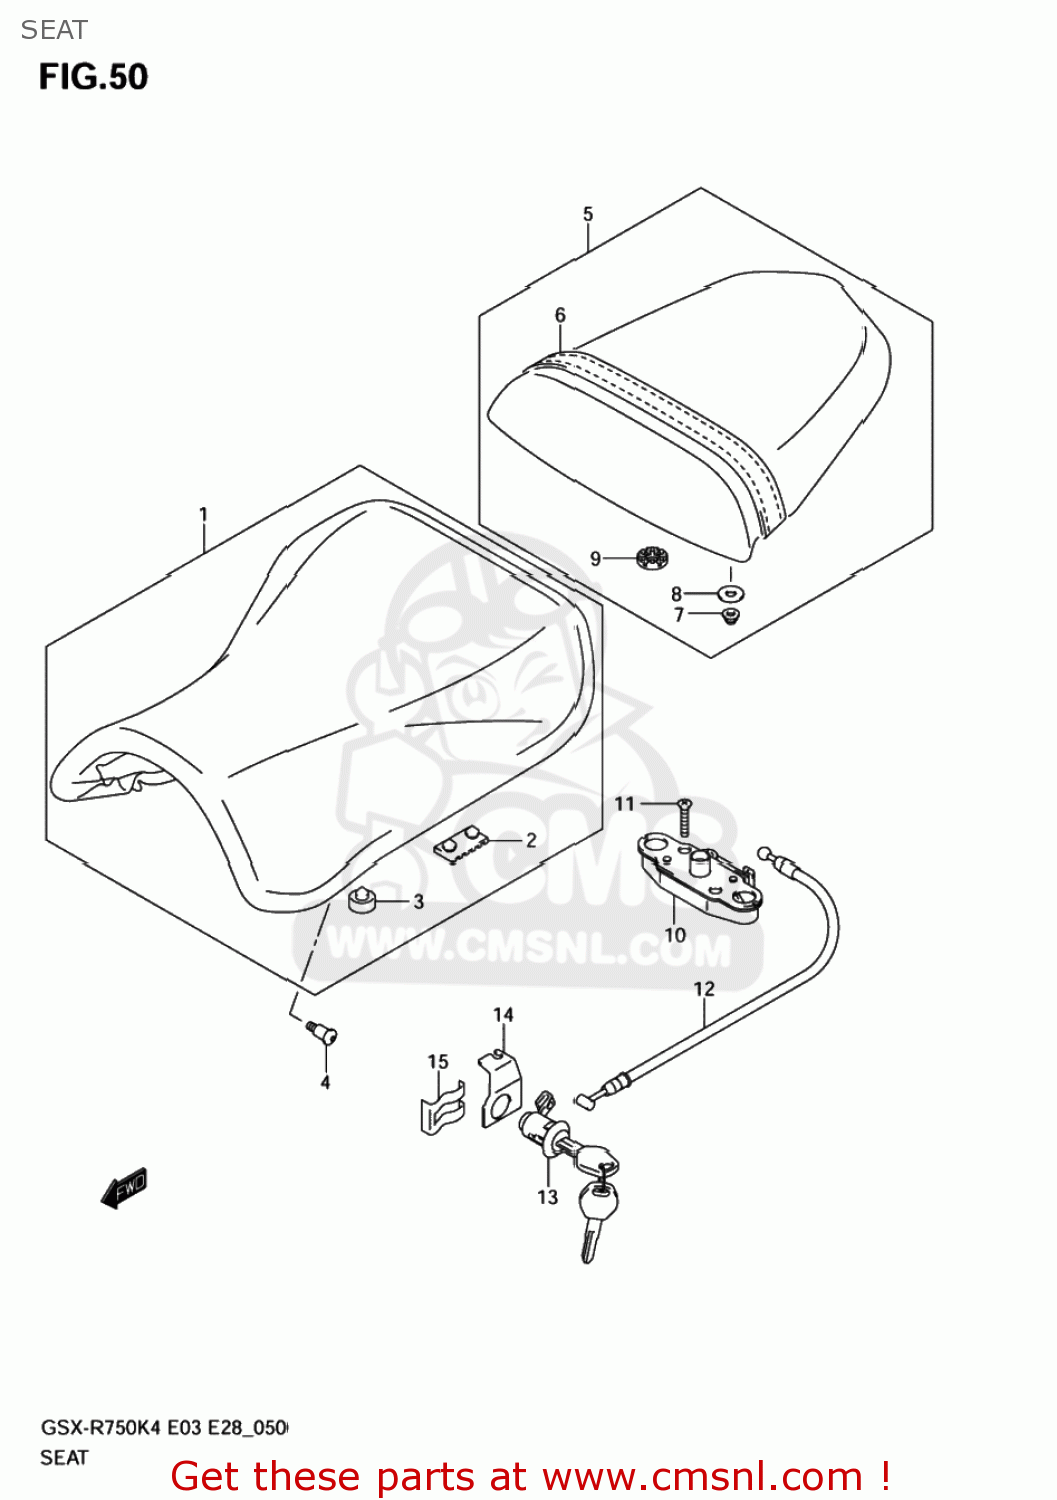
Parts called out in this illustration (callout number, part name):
1	SEAT ASSY
2	CUSHION,SEAT(40X20X6)
3	CUSHION
4	SCREW(6X22)
5	SEAT ASSY,PILLION
6	BAND ASSY
7	NUT
8	WASHER(6.5X20X1.6)
9	CUSHION
10	BRACKET,SEAT SUPPORT,RIGHT
11	SCREW
12	CABLE,SEAT LOCK
13	LOCK SET,SEAT
14	GUIDE,SEAT LOCK CABLE
15	PLATE,SEAT LOCK ASSY
